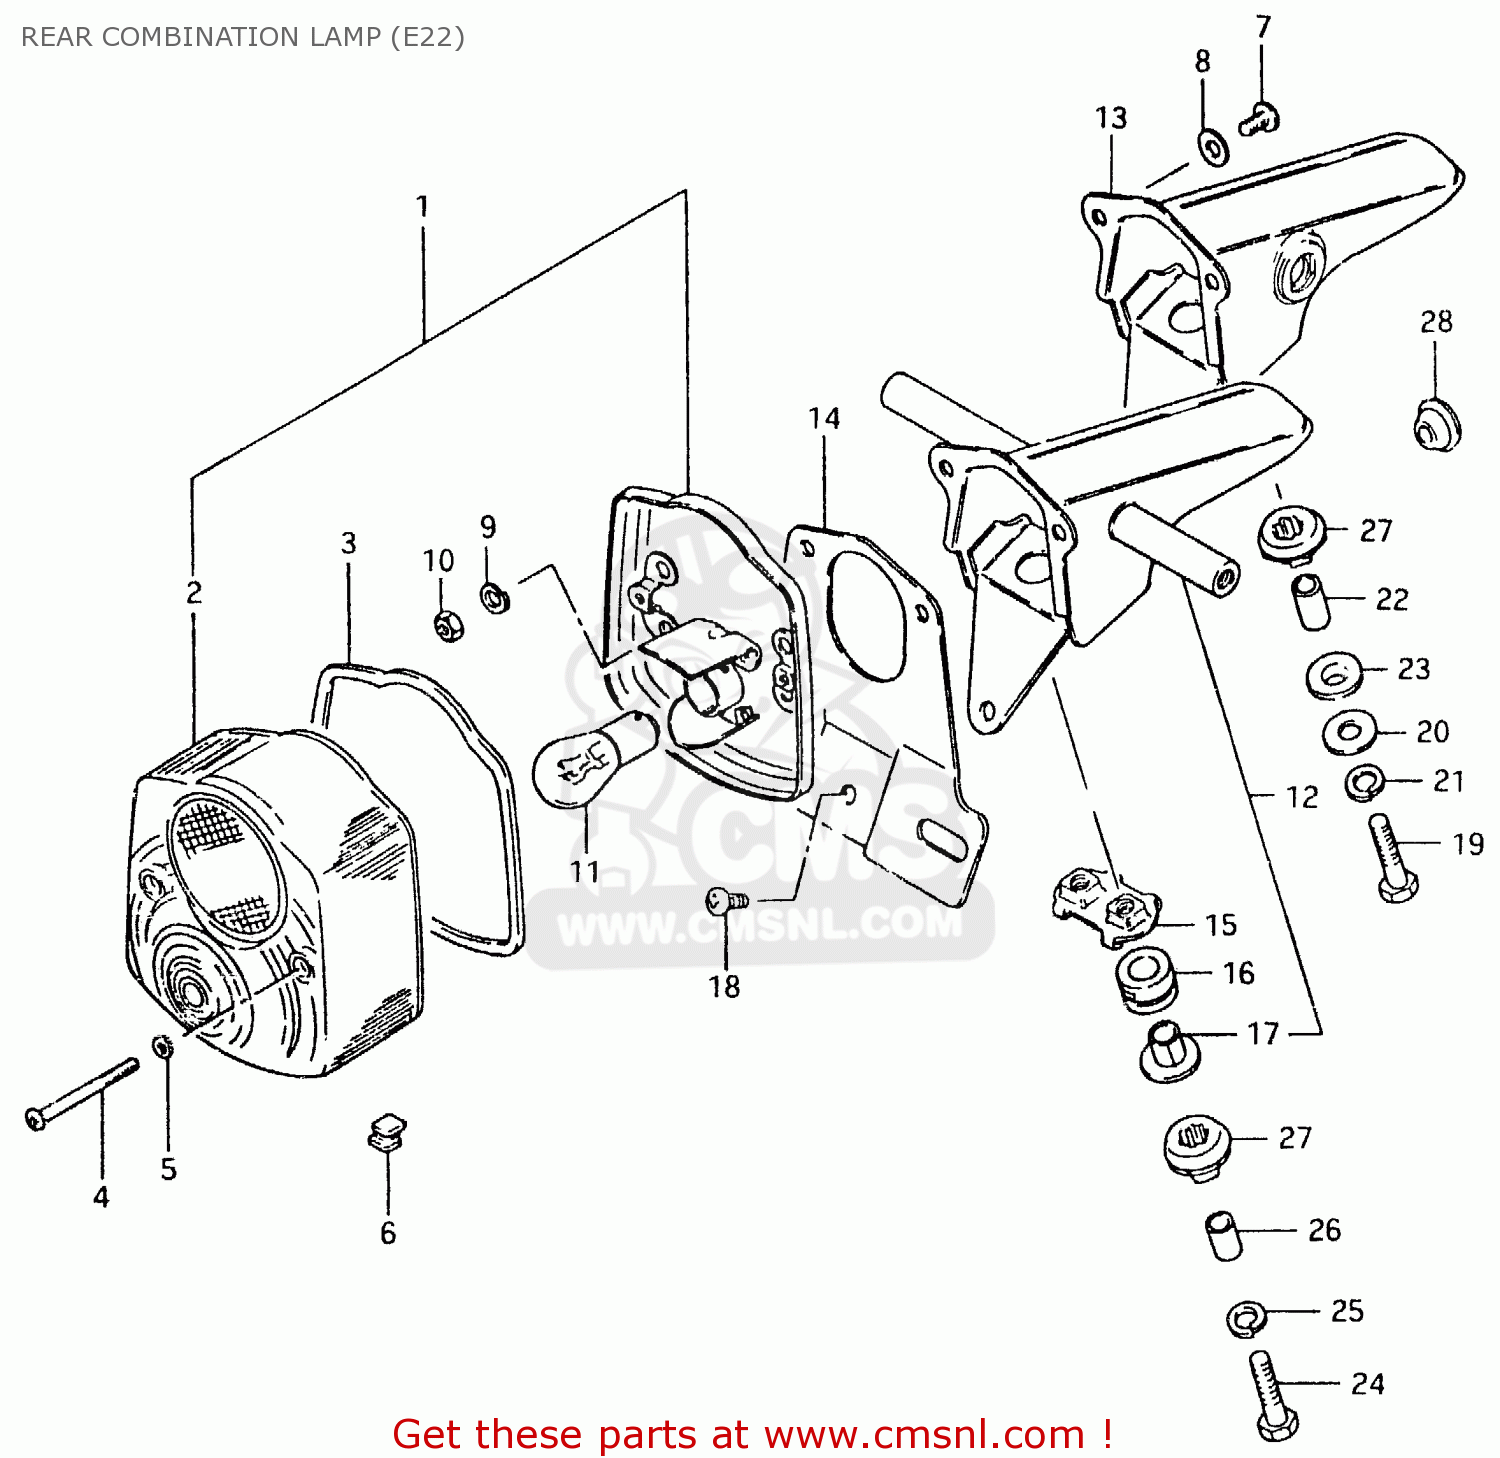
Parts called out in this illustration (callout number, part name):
1	LAMP UNIT, TAIL
2	LENS
3	GASKET (NAS)
4	SCREW
5	GASKET (NAS)
6	GROMMET
7	SCREW
8	WASHER
9	LOCK WASHER
10	NUT
11	BULB (6V,21/5W)
12	BRACKET ASSY
13	BRACKET ASSY
14	PLATE, LICENSE
15	PLATE
16	CUSHION
17	SPACER
18	SCREW
19	BOLT
20	WASHER (6.5X20X1.2)
21	LOCK WASHER
22	SPACER
23	CUSHION
24	BOLT 6X40
25	LOCK WASHER
26	SPACER (6.8X10X11.5)
27	CUSHION
28	GROMMET
